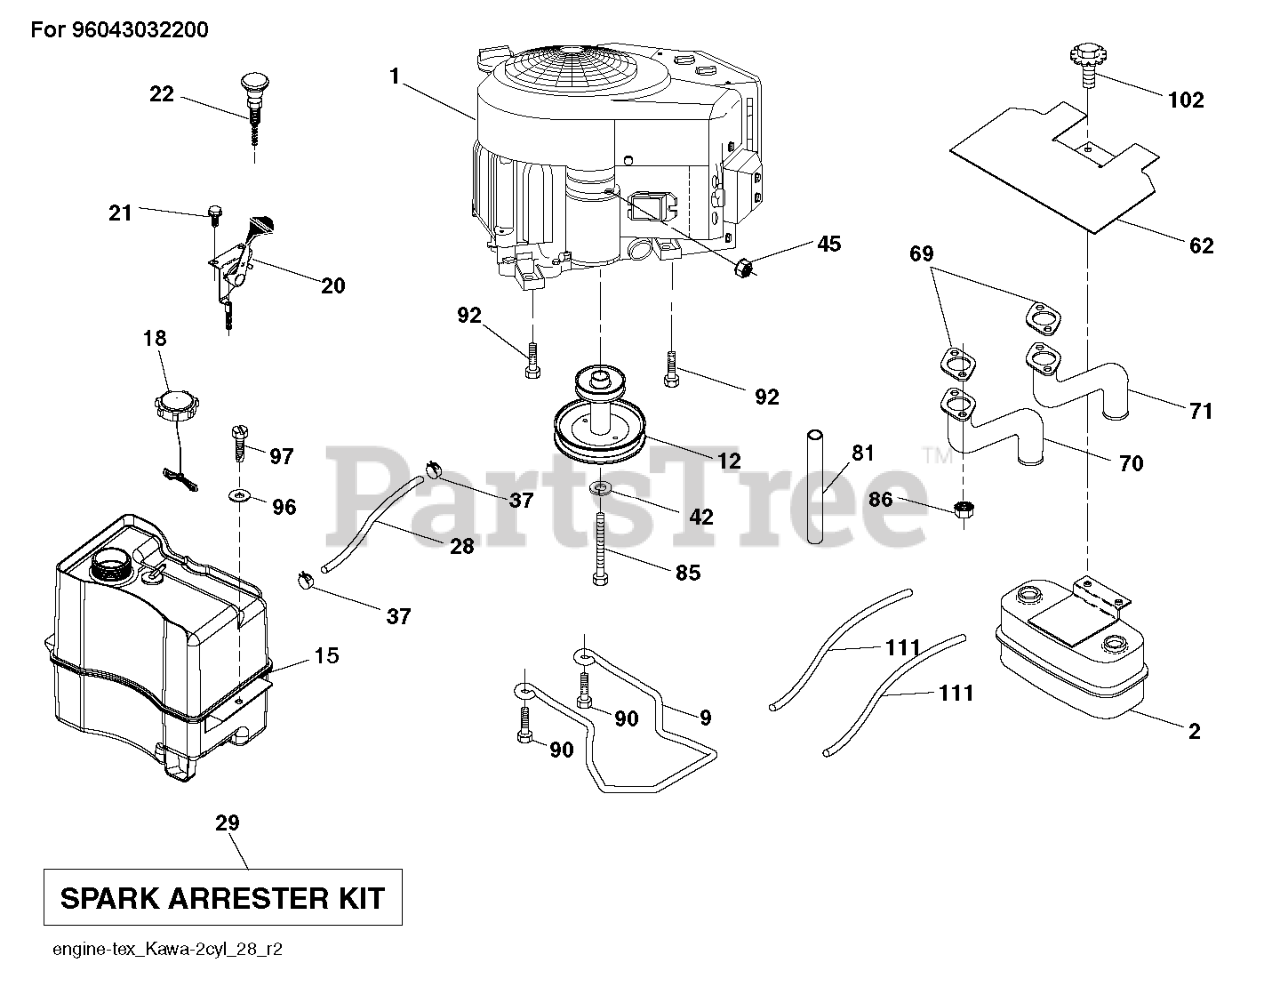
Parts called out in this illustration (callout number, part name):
2	MUFFLER.ASM.TWIN.MNTG.BRACKET
9	Keepers
9	KEEPER.BELT.ENG.4.25"2.BLT.431
12	ENGINE.PULLEY
15	FUEL TANK
15	Tanks
15	FUEL TANKS
18	FUEL.CAP.ASM.2.25TETHRED.RATCH
18	FUEL CAP
20	CONTROL.THROTTLE.COBRA.BLACK
22	CONTROL, CHOKE
28	LINE.FUEL.20
29	KIT.SPARK ARRESTOR 794945 B&S
37	HOSE CLAMP
62	SHIELD.HEAT.MUFFLER
70	TUBE.EXHAUST.LH.FR961/FR730
71	TUBE.EXHAUST.RH.FR961/FR730
81	TUBE, DRAIN OIL ASM.
85	BOLT.HEX.7/16-20X4.GR5.1.5BLUE
86	NUT.HEX.FLANGE.TOPLOCK
90	SCREW 3/8-16X1
92	SCREW 3/8-16X1
97	SCREW HEXWSHR 1/4-20X3/4
102	SCREW
111	TUBE.PURGE.FUEL.1875
